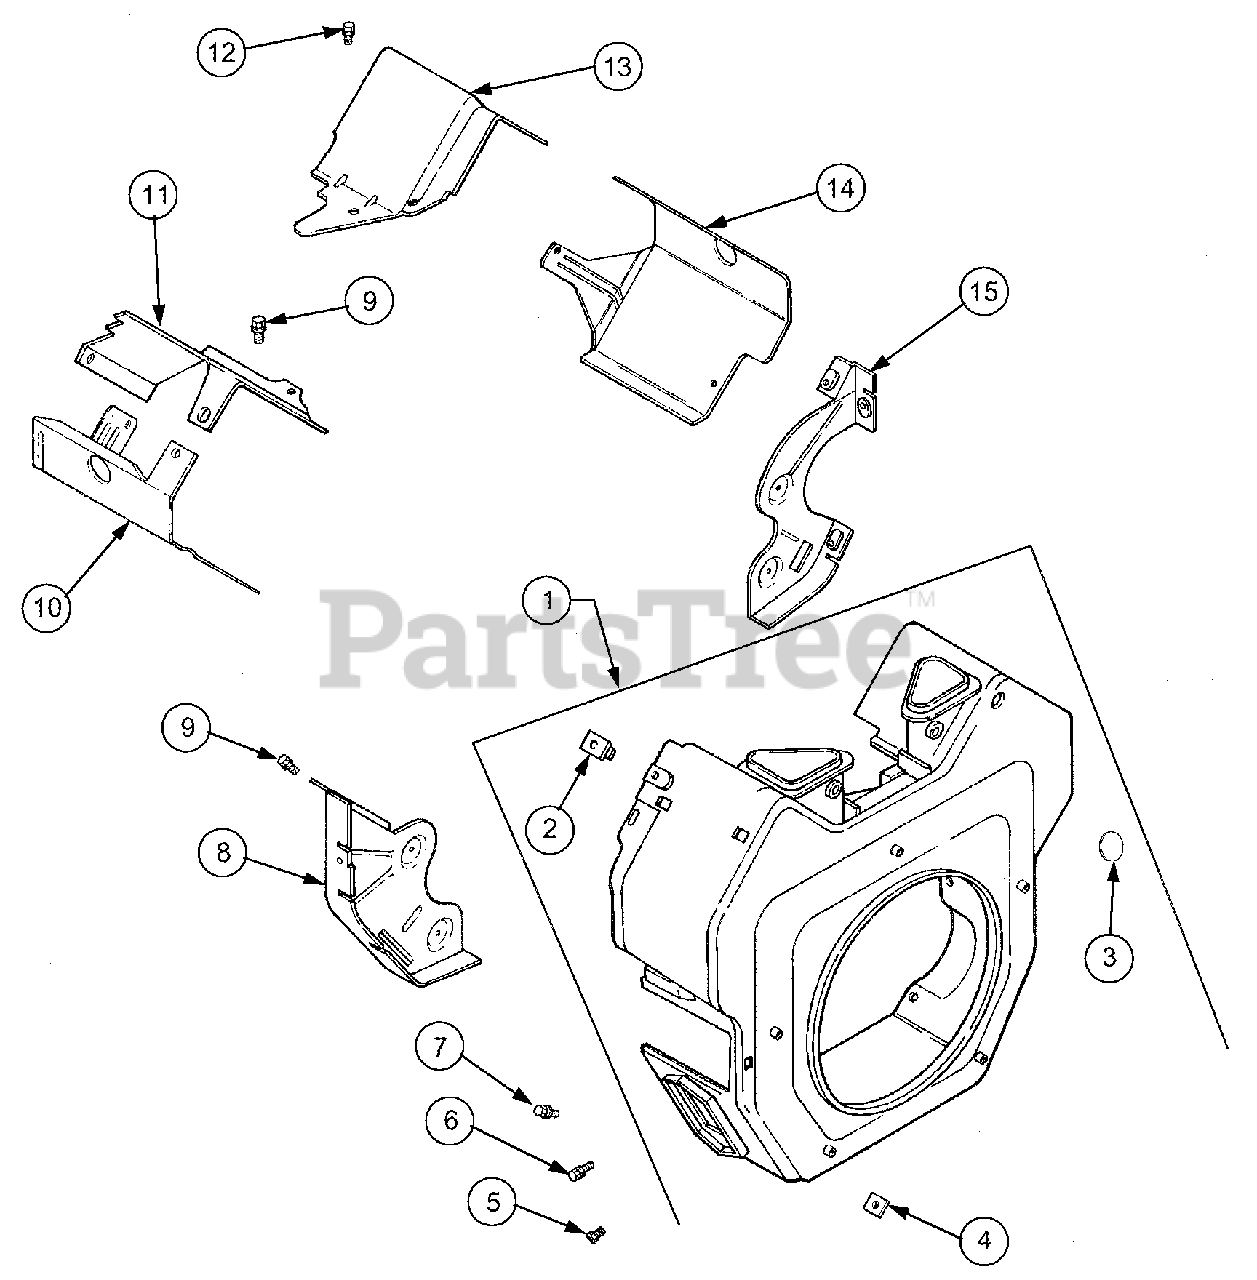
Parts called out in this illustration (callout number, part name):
1	Housing, Blower
2	Nut, Plastic
3	Plug, Button, 9/16
4	Nut, Plastic
5	Screw, Hex Flange, M5 x 0.8 x 16
6	Screw, Hex Flange, M5 x 0.8 x 16
7	Screw, Hex Flange, M5 x 0.8 x 20
8	Plate, Backing - #2 Side
9	Screw, Hex Flange, M6 x 1.0 x 16
10	Baffle, Cylinder Barrel - #2 Side
11	Baffle, Valley - #2 Side
12	Screw, Hex Flange, M5 x 0.8 x 10
13	Baffle, Valley - #1 Side
14	Baffle, Cylinder Barrel - #1 Side
15	Plate, Backing - #1 Side
